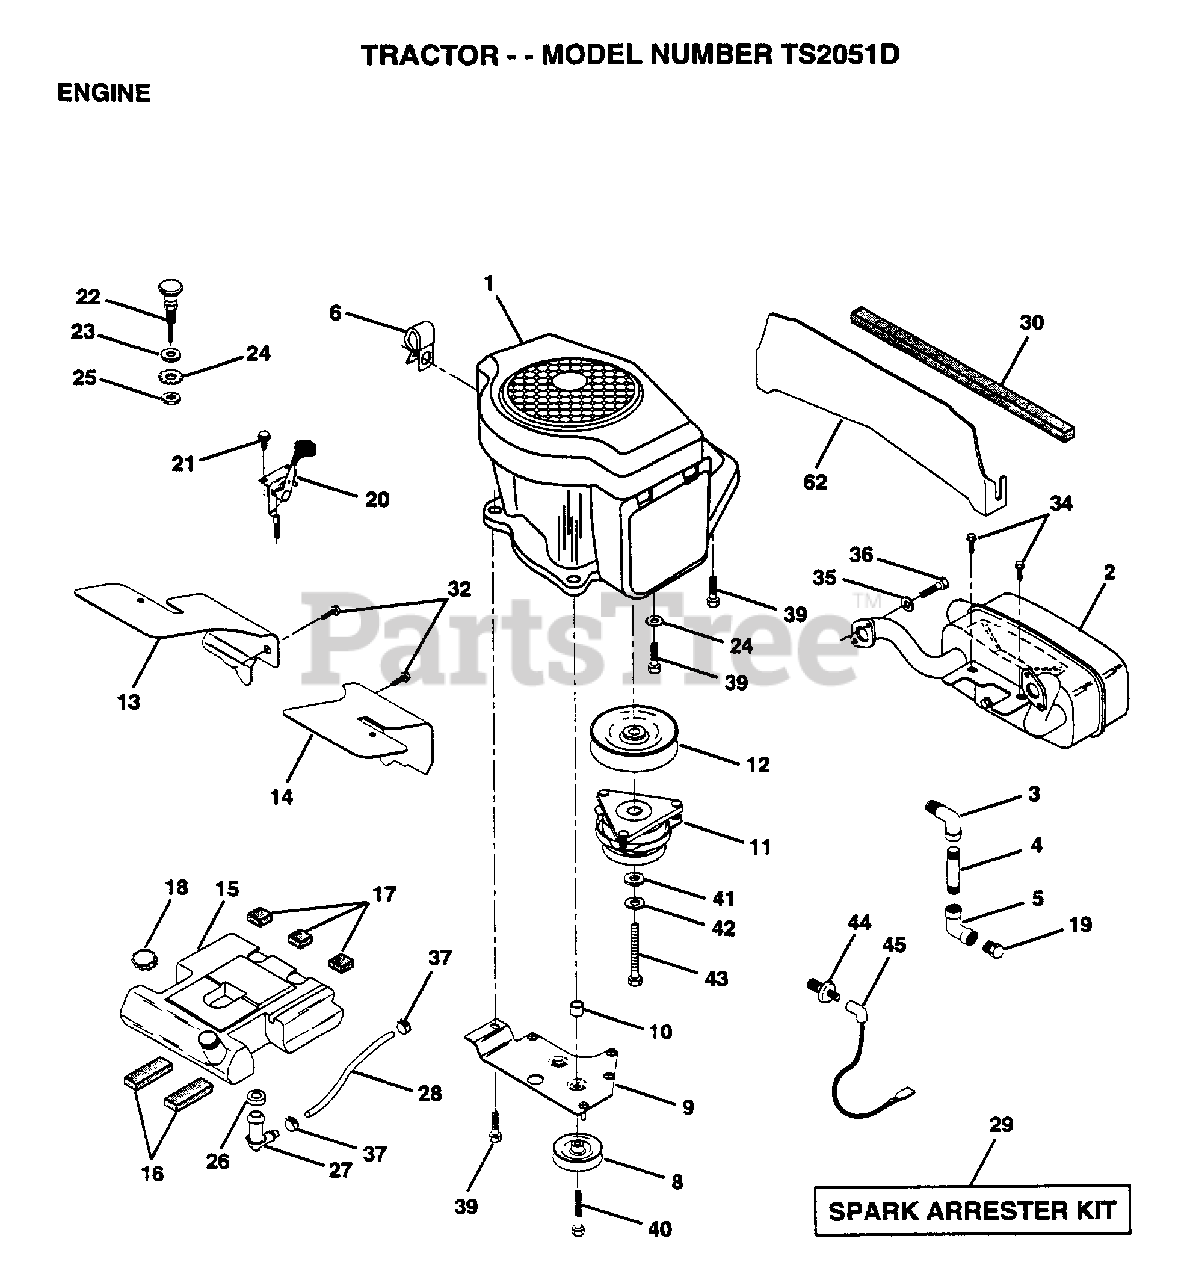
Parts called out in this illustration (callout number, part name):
1	ENGINE KOHLER MODEL
2	MUFFLER.KOH.VCT.
3	STREET ELBOW LT
4	PIPE NIPPLE
5	ELBOW
6	CLAMP.TUBE.DBL.EN
10	BUSHING.
12	PULLEY.ENGINE.VGT
13	BAFFLE.AIR.LH.K
16	PAD IDLER TI
17	PAD-SPACER LT
18	CAP ASM FUEL
19	PLUG T
20	CONTROL THTL 37
21	SCREW LT
22	"CONTROL.CHOKE.51"""
23	WASHER
24	LOCKWASHER
26	BUSHING OUTLET T
27	STEM.TANK.FUEL
29	SPARK ARREST KIT
32	SCREW LT
34	SCREW
35	LOCKWASHER
36	SCREW
37	HOSE CLAMP
39	SCREW LT
40	SCREW.3/8-16X3.25
41	WASHER
42	LOCKWASHER
44	SWITCH OIL KOHLER
45	WIRE LEAD KOHLER
62	SHIELD.HEAT.MUF
